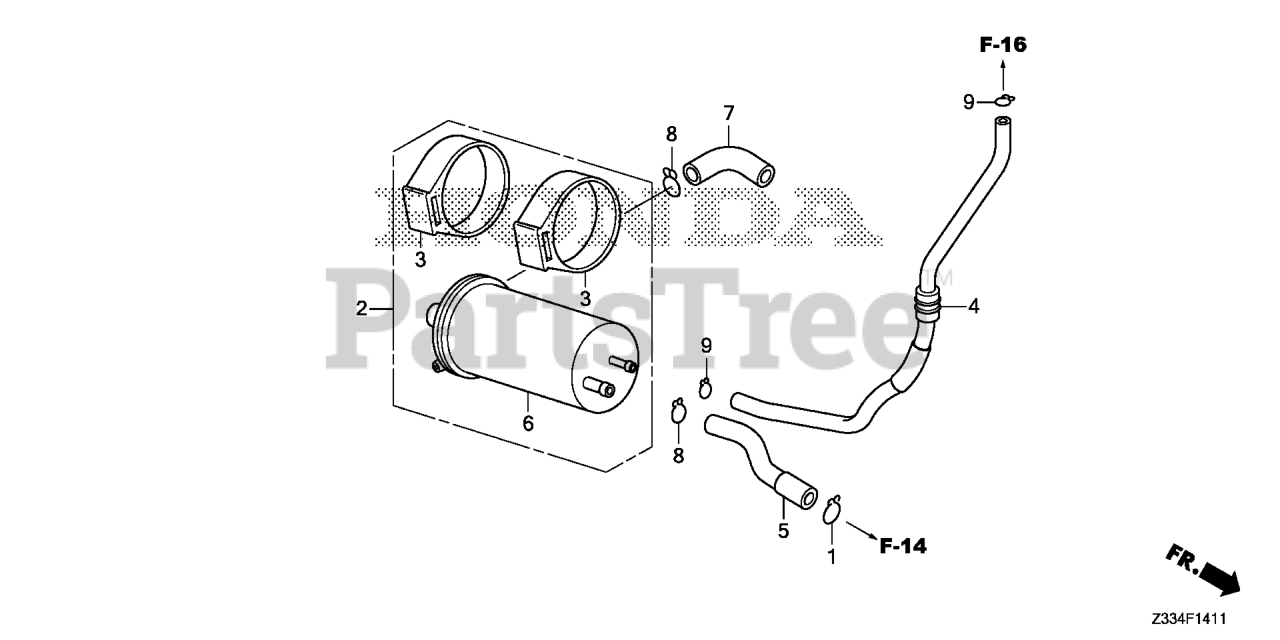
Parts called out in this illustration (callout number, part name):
1	CLIP, BREATHER TUBE
2	CANISTER ASSY.
3	RUBBER, CANISTER MOUNTING
4	TUBE CANISTER CHARGE
5	TUBE, CANISTER PURGE
6	CANISTER ASSY.
7	TUBE, CANISTER DRAIN
8	CLIP, TUBE
9	CLIP, TUBE (B8)
